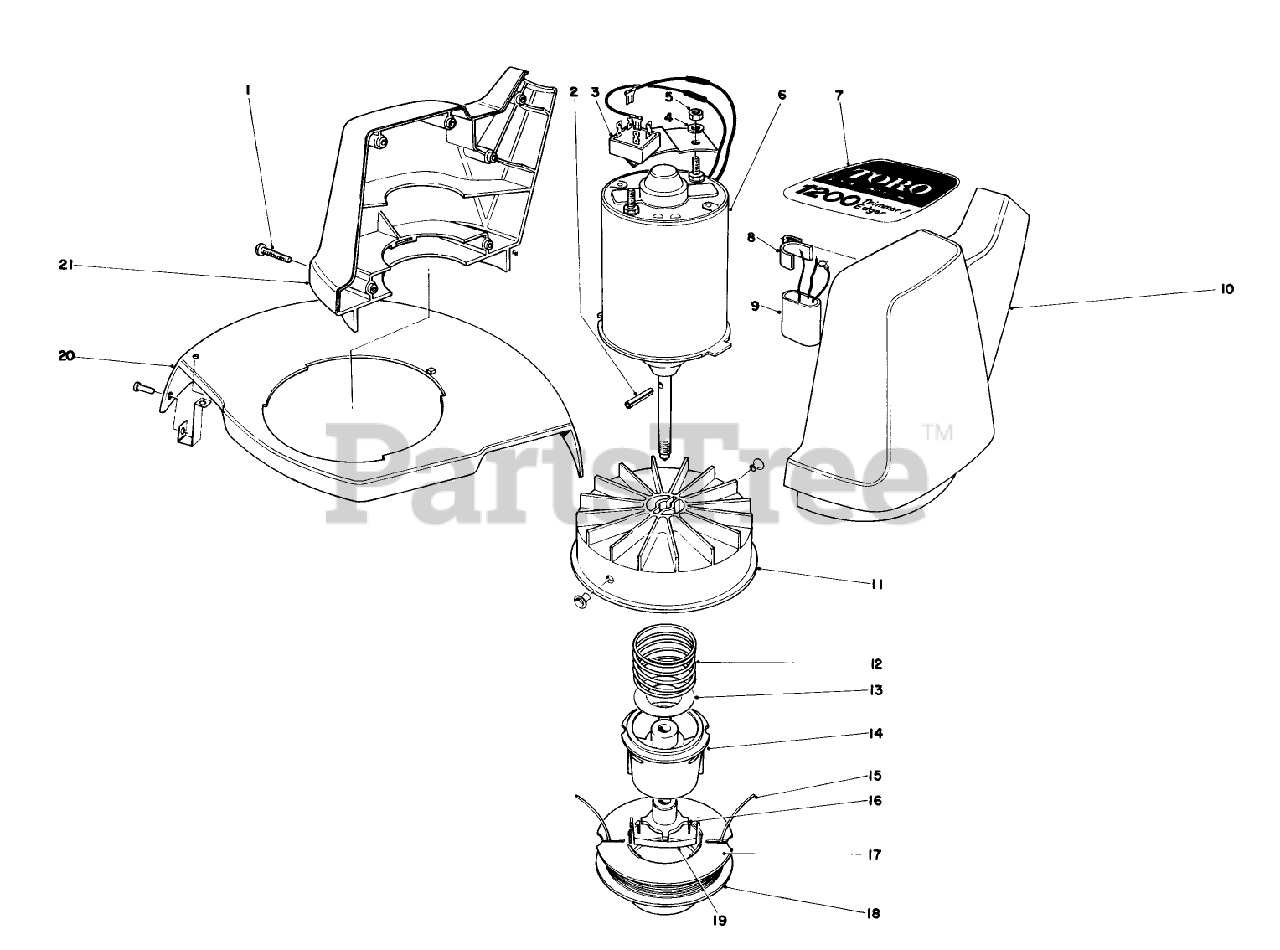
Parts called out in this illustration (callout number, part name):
1	SCREW-PPH
2	COIL PIN
4	WASHER-LOCK, EXT
5	NUT-HEX
12	SPRING COMPRESSION
13	WASHER-FLAT
14	SPOOL CORE
18	Prewound Spool (Incl. Ref. #9)
